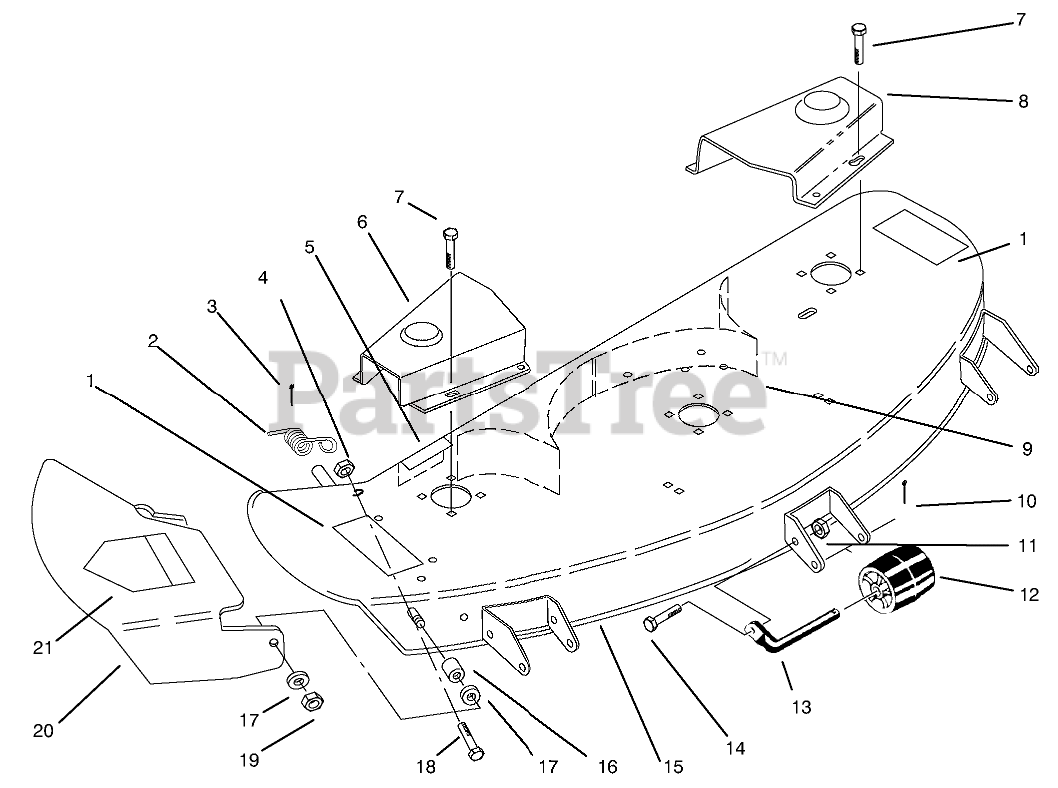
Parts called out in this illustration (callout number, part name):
1	DECAL-DANGER
2	SPRING-DEFLECTOR
3	PIN-COTTER
4	NUT-LOCK, NI
5	Decal-Height & Belt
6	Belt Cover RH
7	SCREW-HWH
8	Belt Cover LH
9	BAFFLE-DECK R.H.
10	PIN-COTTER
11	NUT-LOCK, NI
12	ROLLER ASSY
13	ROLLER-SHAFT
14	SCREW-HH
15	Deck-Mower (Incl. Ref. #1)
16	BUSHING-PIVOT
17	WASHER
18	SCREW-HH
19	NUT-HJ
20	Extension-Chute (Incl. Ref. #21)
21	DECAL-DANGER
